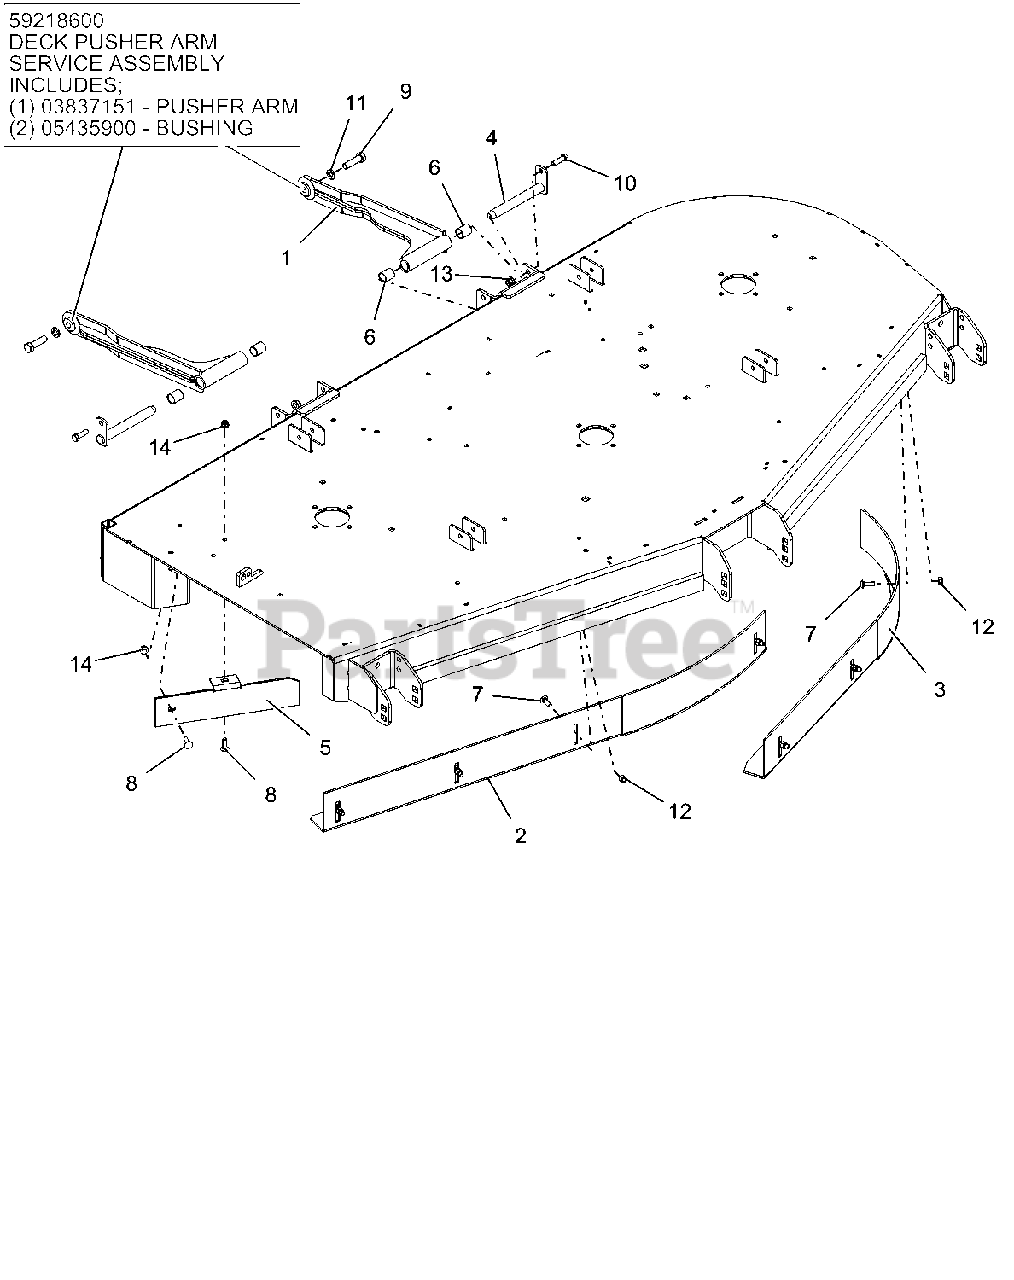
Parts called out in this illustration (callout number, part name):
1	DECK PUSHER ARM SERVICE ASSEMBLY
1	PUSHER ARM
1	BUSHING
1	WLDMT, DECK STABILIZER ARM
2	WLDMT, BAFFLE 72 VACUUM RIGHT (BLACK)
3	WLDMT, 72" LH VACUUM BAFFLE (BLACK)
4	WLDMT, MOWER MTG. PIN
5	BAFFLE, DISCHARGE 72" (RED)
6	BRG, .750 X .875 X 1.000
7	BLT-RDHDSQSHNK .31-18X1.00 G5 Y
8	BLT-RDHDSQSHNK .31-18X1.00 G5 Y
9	BLT-HEX .50-13X1.75 GR5 YWZC EP80
10	BLT-HEX .38-16X1.25 GR5 YWZC
11	WSHR-LK .50X.125 REG YWZC
12	NUT-LK-NYL .312-18 YWZC
13	NUT-LK-NYL-FLG .38-16 YWZC
14	NUT-LK-NYL-FLG .31-18 YWZC
